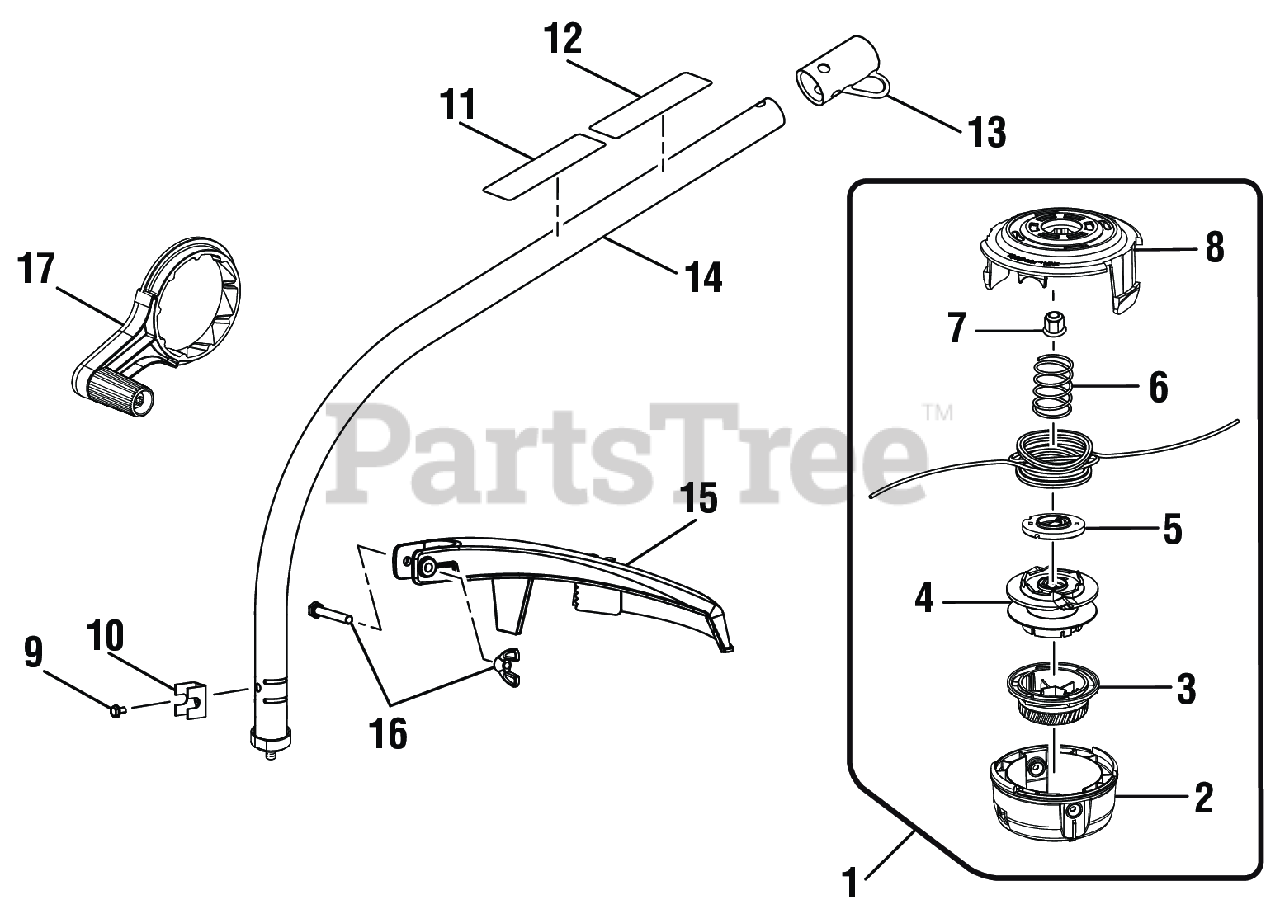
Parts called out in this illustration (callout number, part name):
1	Trimmer Head Assembly (.095)
2	Lower Housing
3	Bump Knob (Green)
4	Spool Assembly
5	String Guide
6	Compression Spring
7	Flange Nut (M8)
8	Upper Housing
9	Screw (#10-32 x 3/8 in., Hex Washer Hd. S.T.)
11	Ryobi EXPAND-IT Label
12	Warning Icon Label
13	Storage Hanger Cap
14	Curved Shaft Assembly
15	Grass Deflector Assembly
16	Fastener Parts Kit
17	Crank Handle
